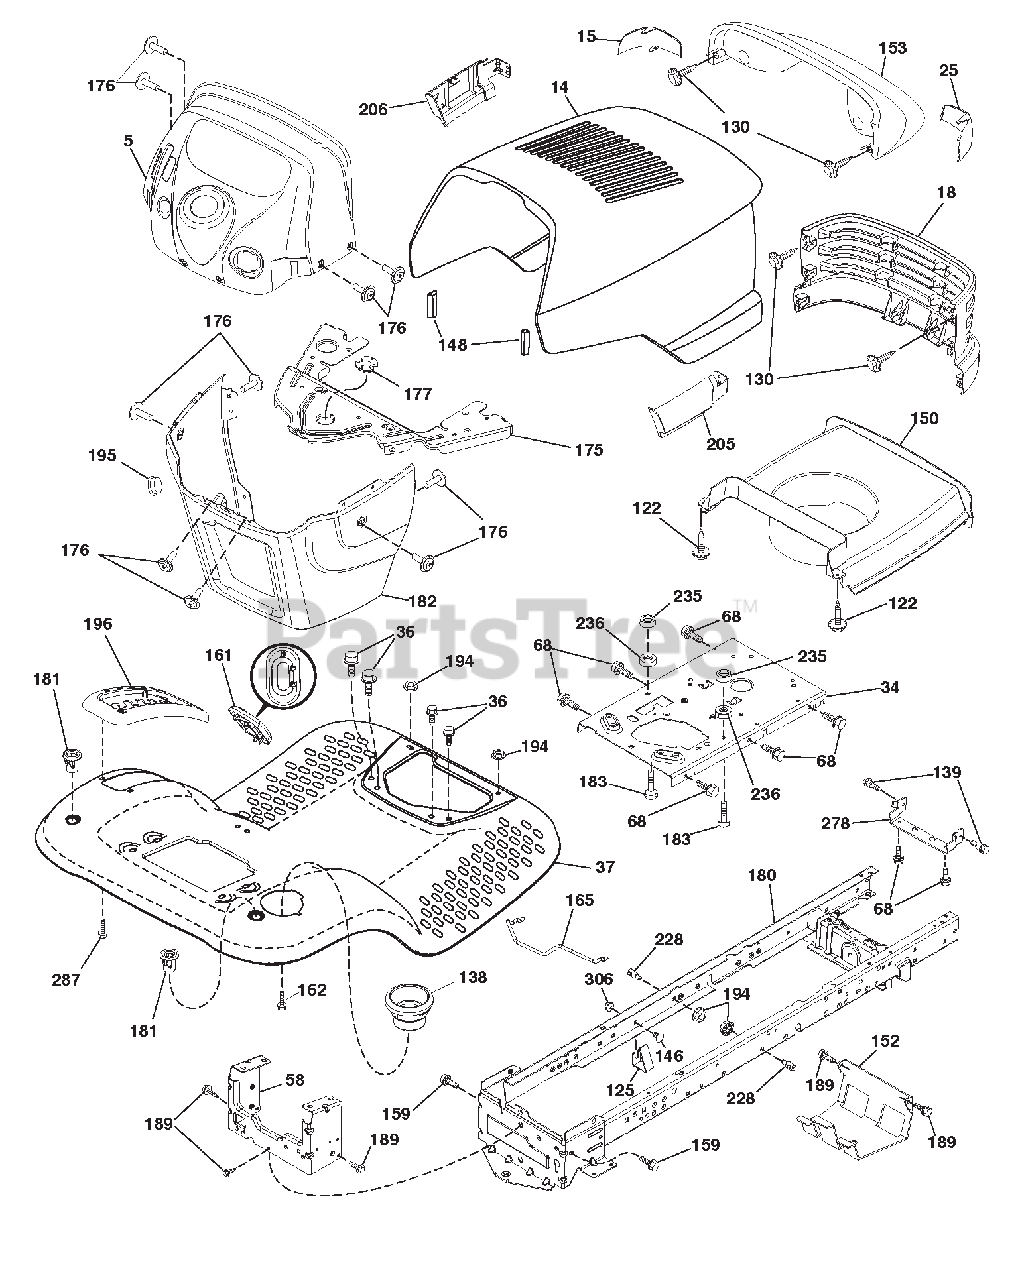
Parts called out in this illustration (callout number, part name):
15	LENS ELITE ARIENS BLACK
25	LENS ELITE HUSQ CLEAR RH
34	PLATE.ENGINE.WELDED.CHASSIS
36	SCREW.5/16-18X3/4.SMGML.TAP/R
58	DRAWBAR.UPPER.2PC.SML.FENDER
68	SCREW.THDROL.5/16-18 X 1/2TYTT
122	SCREW TO 32 X 5/8
125	CLIP.FUEL.LINE
138	CUPHOLDER TL TEX 428
139	BOLT SHOULDER 5/16-18
148	BUMPER HOOD LARGE 1.75
150	AIR DUCT ENGINE ELITE SV
152	SHIELD.BROWNING.W/TEX
153	ASM LIGHT BOX
159	SCREW.HEXWSH THDR3/8-16X3/4.BL
161	WINDOW FUEL
162	SCREW.HEX.WSH.HI-LO.1/4X1/2UNC
165	SUPPORT.TANK.REAR.W/TEX
175	CROSSMEMBER LT
176	SCREW.#10-24X5/8.RND.QUDRX.GIM
177	BUSHING.STEERING.YT/GT
180	CHASS.WLDMT.TL.12GA/2PC.18/22"
181	BUSHING MNT FEND CRGO BLK TEX
182	DASH TOWER LT CCS
183	BOLT.FIN.HEX.5/16-18 UNC X1-1/
189	SCREW.5/16-18X3/4.SMGML.TAP/BL
194	Nut, Lock Hex Flange 5/16-18 u
195	PLUG HOLE DASH TOWER
196	CONSOLE ASM.DECKLFT.BL/RBT.TLT
205	SKIRT SIDE RH
206	SKIRT SIDE LH
228	STUD.FASTNER.W/'D'ANTI-ROTATIO
235	SPACER.FENDER
236	NUT.CENTER LOCK.5/16-18 UNC
278	X-PIECE HOOD
287	SCREW.HEX.WASHEAD.1/4-20 X 3/8
306	Nut, Hex, Flangelock 3/8-16
